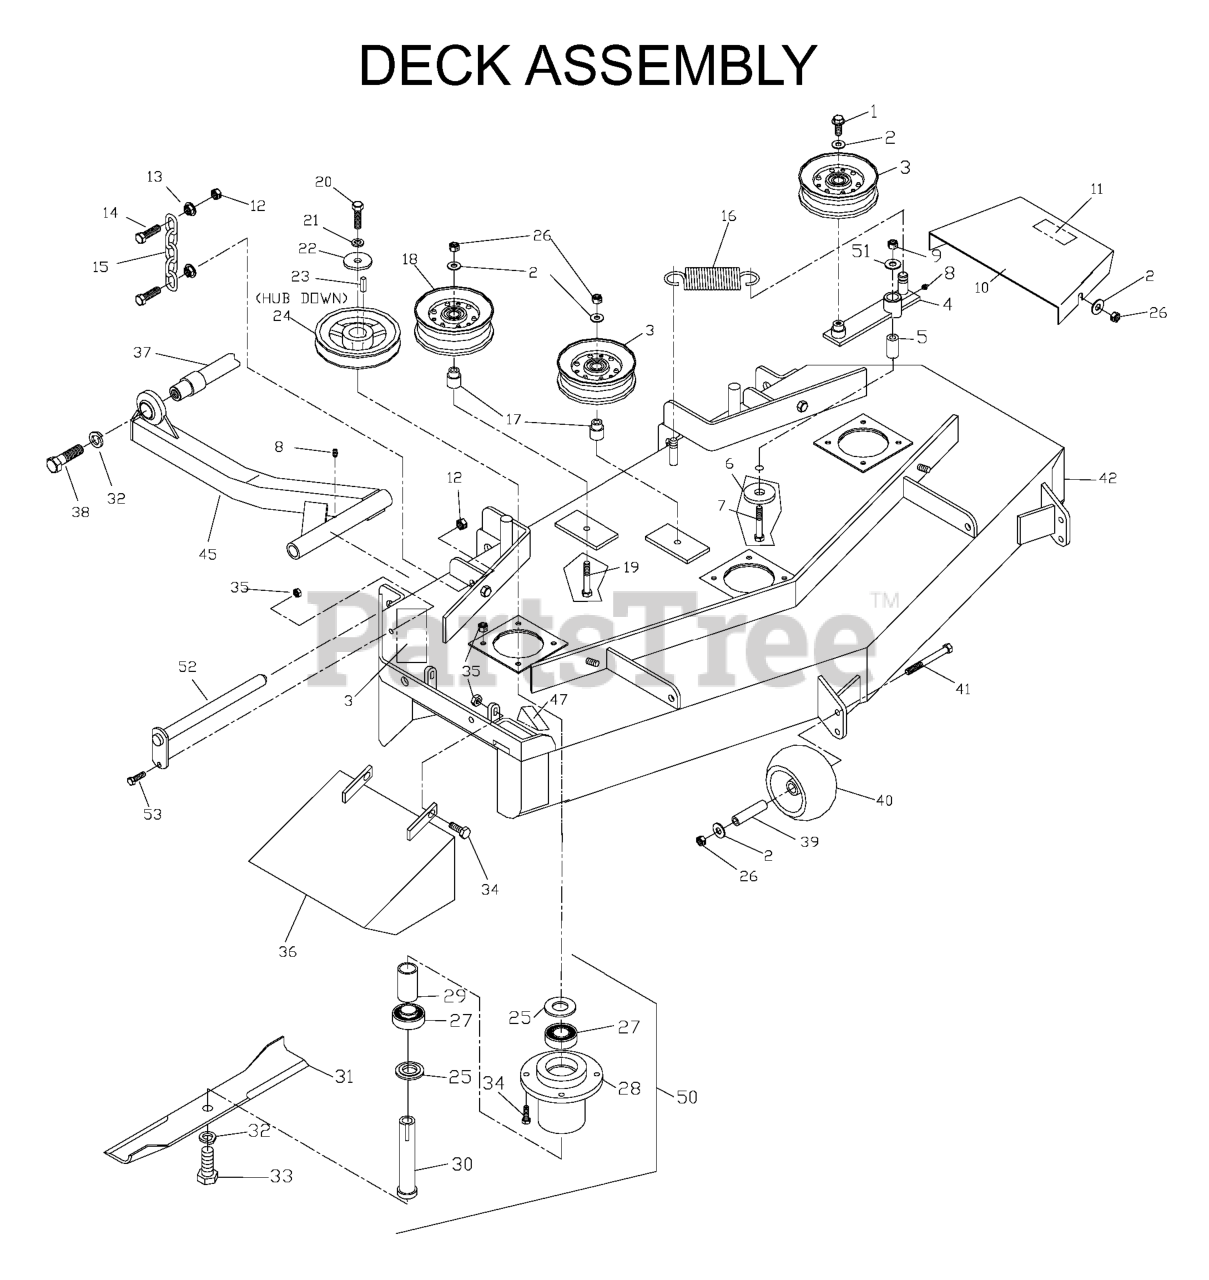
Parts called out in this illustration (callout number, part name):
1	4CS 3/8C X 1 SERRATED HEAD
2	WASHER 3/8 FLAT
3	IDLER PULLEY
5	PIVOT BUSHING
6	WASHER, SUPPORT
7	HCS 1/2C X 3 1/4
8	ZERK
9	NUT 1/2-13 HEX NYLOC ZD
10	BELTSHIELD
11	DECAL, NO STEP
12	NUT 7/16C CENTERLOCK
13	NUT 7/16C WHIZ
14	HCS 7/16C X 1 1/2
15	LIFT CHAIN
17	IDLER BUSHING
18	IDLER PULLEY (TALL)
19	HCS 3/8C X 2 1/2
20	HCS 7/16F X 1 1/2
21	WASHER 7/16 LOCK
22	SPINDLE WASHER
23	KEY 1/4 SQ X 1 1/8
25	MACHINERY BUSHING 10 GA.
26	BUSHING.MACHINE.18.GAUGE
27	BEARING
28	HOUSING, DIE CAST
30	SPINDLE SHAFT
31	BLADE OEM 16 1/4"
32	LOCKWASHER 5/8
33	HCS 5/8F X 1 1/4
34	HCS 5/16C X 1
35	NUT 5/16C CENTERLOCK
36	DEFLECTOR CHUTE
37	STRUT MOUNT WELDMENT
38	HCS 5/8C X 2 GR.5
40	ANTI-SCALP ROLLER
41	HCS 3/8C X 3 1/2
42	DECK W/DECALS
45	STRUT WLDMT - RT
47	DECAL, CPSC
48	DECAL, DANGER
49	DECK BELT 48"
50	HOUSING, COMPLETE
51	WASHER 1/2 FLAT
53	HCS 5/16C X 3/4
55	NUT 3/8C CENTERBLOCK
539104621	STRUT SLDMT-LT
